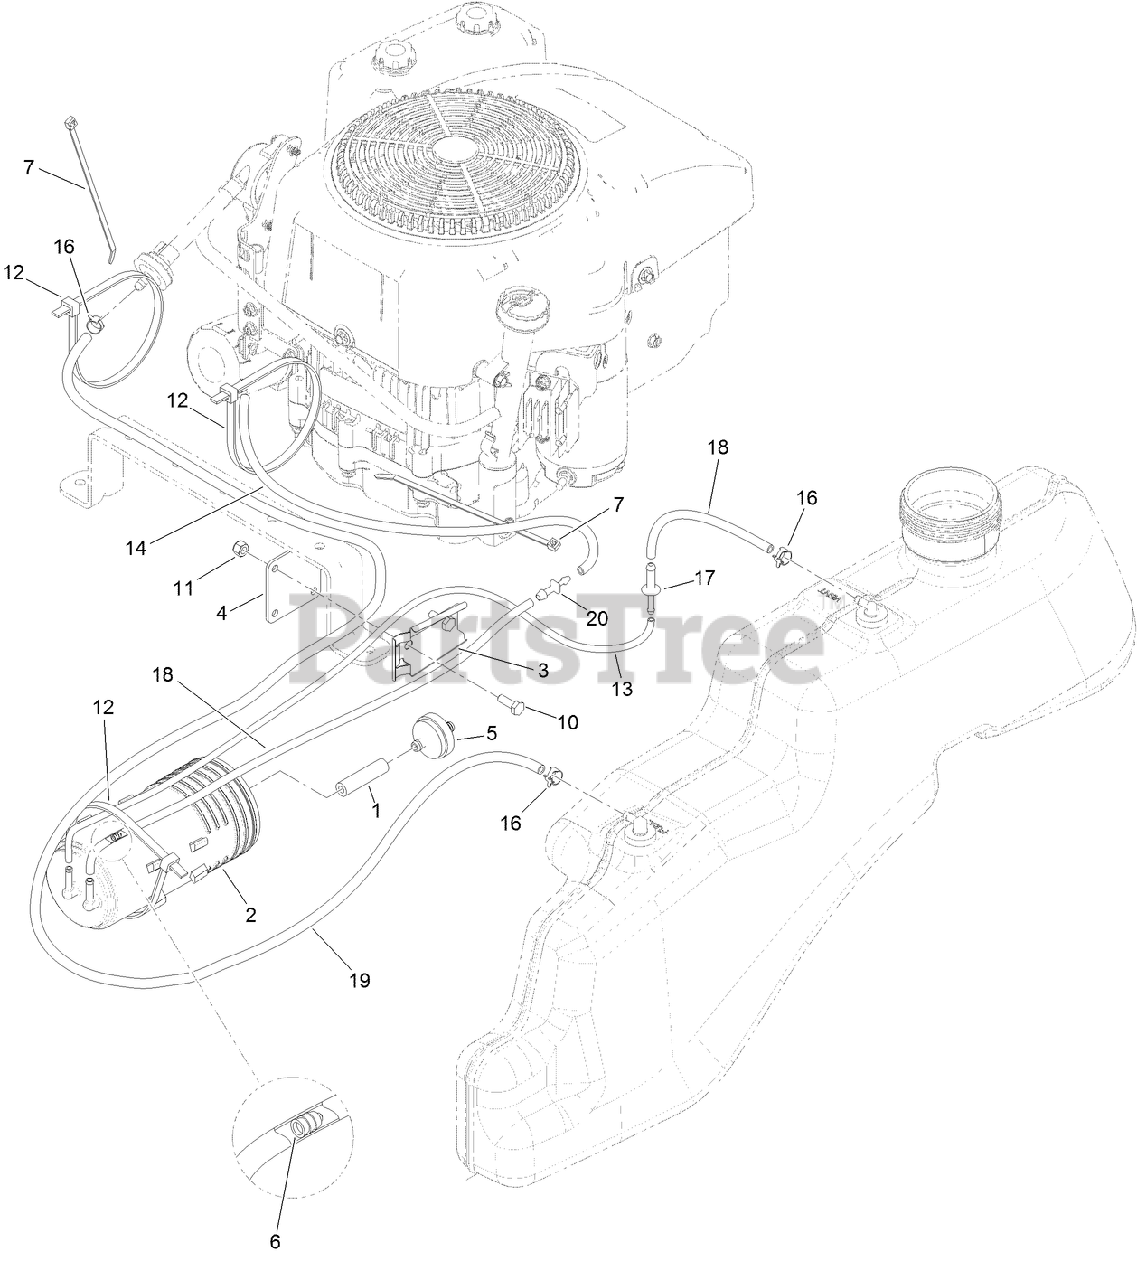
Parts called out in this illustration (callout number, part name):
1	HOSE-FUEL
2	CANISTER-CARBON, 800CC
3	BRACKET-CANISTER, CARBON
4	PLATE-ADAPTER
5	FILTER-FUEL, INLINE
6	CARTRIDGE-VALVE, CHECK
7	TIE-CABLE
10	SCREW-HH
11	NUT-LOCK, NI
12	TIE-CABLE
13	HOSE-FUEL
14	HOSE-FUEL
16	CLAMP-HOSE
17	ADAPTOR-ORIFICE
18	HOSE-FUEL
19	HOSE-FUEL
20	FITTING-STRAIGHT
